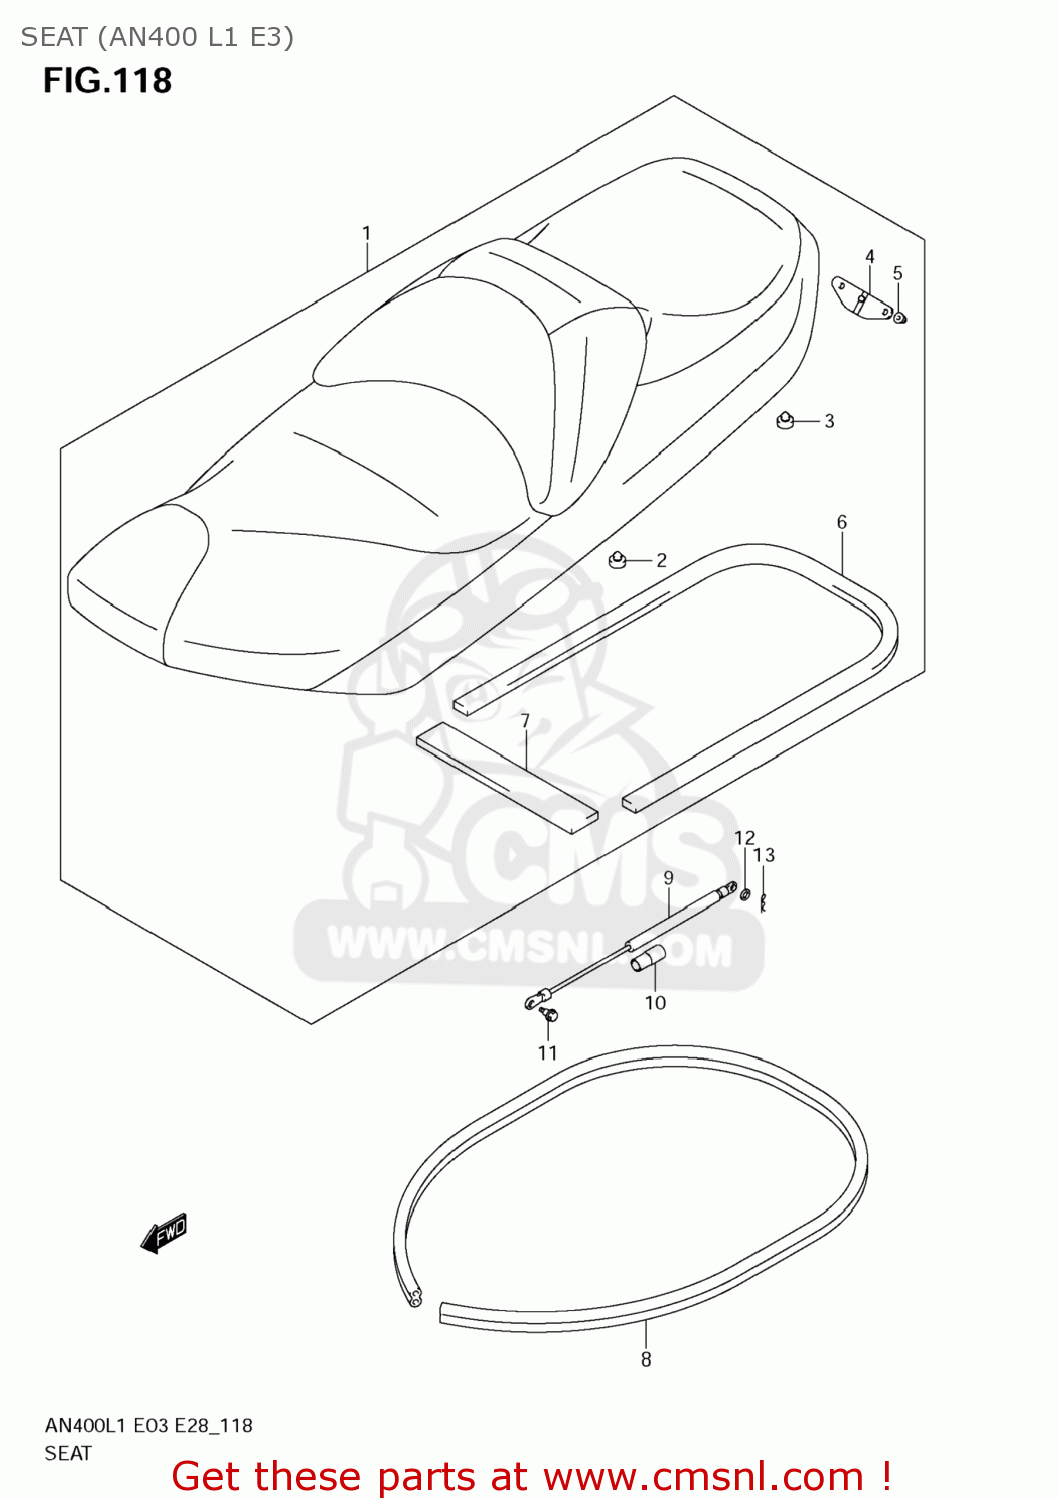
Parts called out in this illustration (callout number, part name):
1	SEAT ASSY
2	CUSHION
3	CUSHION,FR
4	STRIKER,SEAT LOCK
5	NUT
6	CUSHION,SEAT
7	CUSHION,SEAT
8	MOLDING,SEAT
9	DAMPER ASSY,SEAT
10	HOSE(13.5X16.5X600)
11	BOLT(6X16)
12	WASHER
13	SNAP
